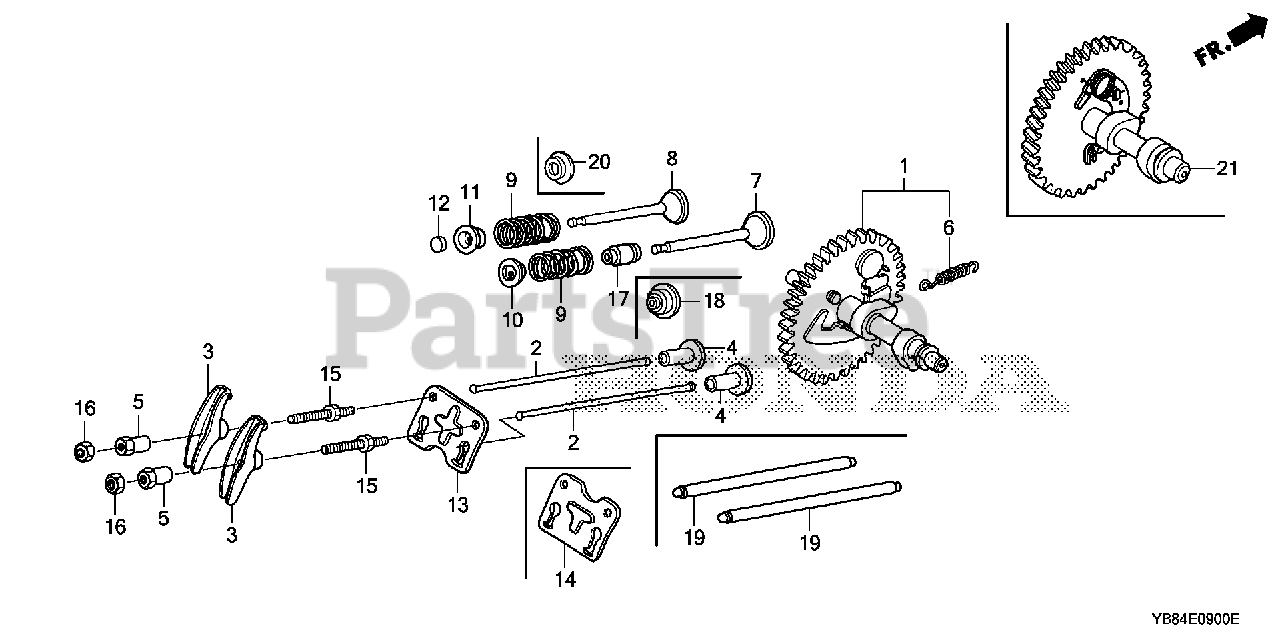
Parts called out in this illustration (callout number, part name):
1	CAMSHAFT ASSY.
3	ARM, VALVE ROCKER
4	LIFTER, VALVE
5	PIVOT, ROCKER ARM
6	SPRING, WEIGHT RETURN
7	VALVE, IN.
8	VALVE, EX.
9	SPRING, VALVE
10	RETAINER, VALVE SPRING (EXHAUST SIDE)
11	RETAINER, VALVE SPRING (EXHAUST SIDE)
13	PLATE, PUSH ROD GUIDE
15	BOLT, PIVOT (8MM)
16	NUT, PIVOT ADJ.
18	SEAL, VALVE STEM
